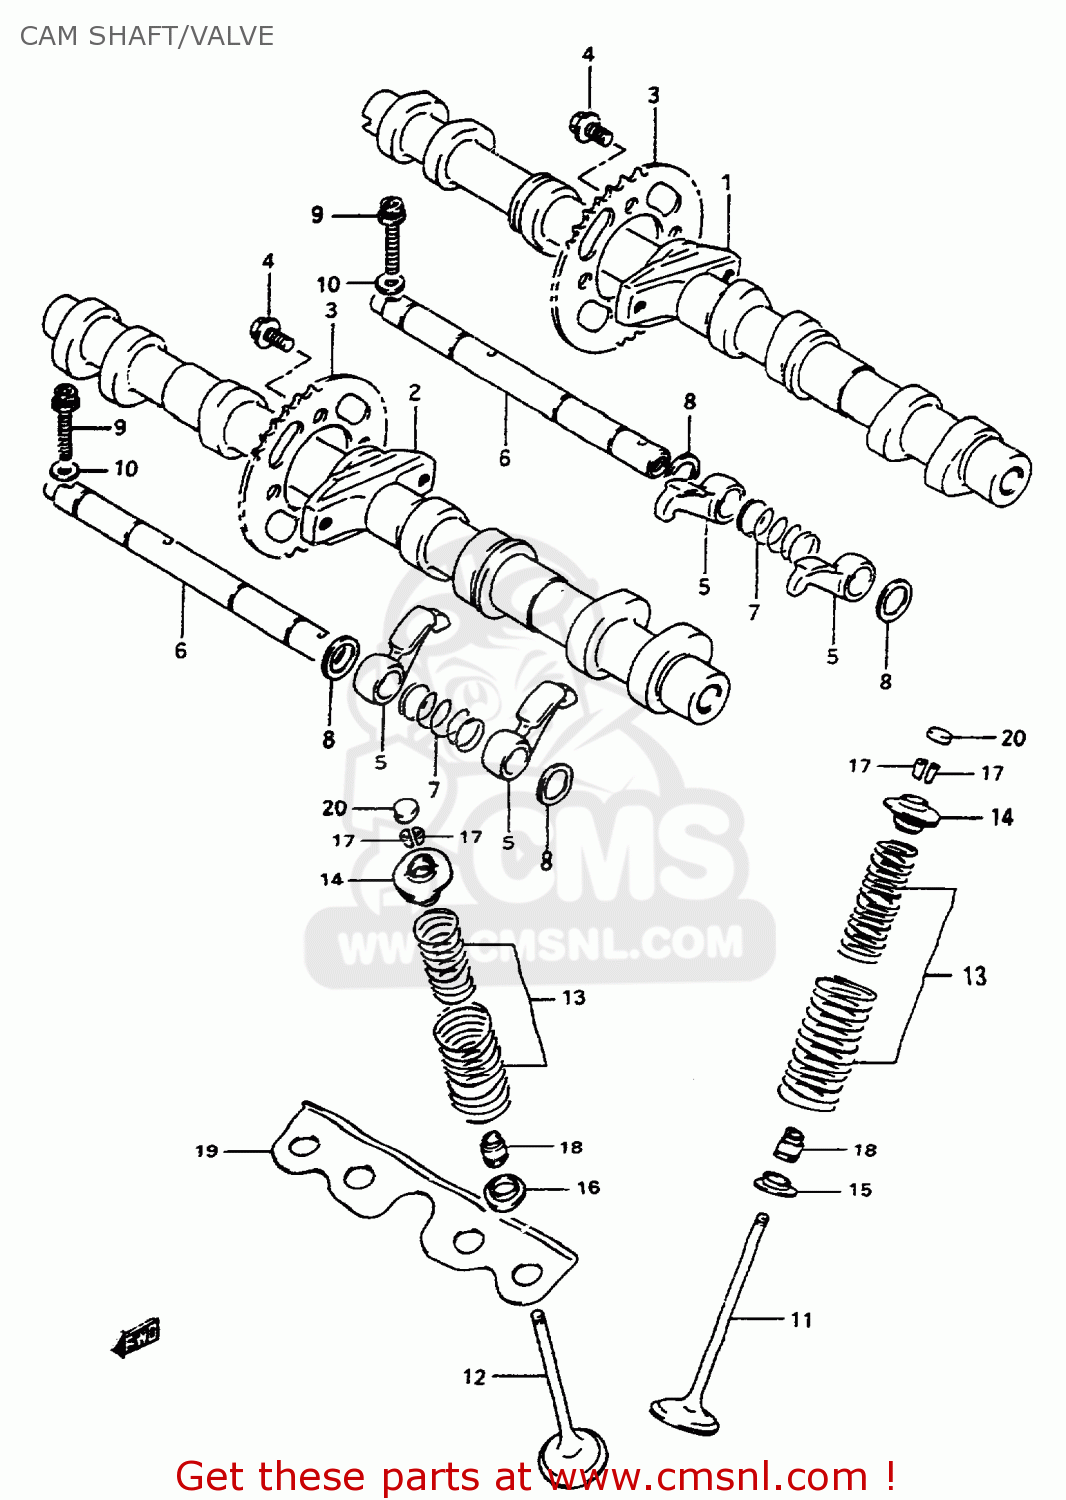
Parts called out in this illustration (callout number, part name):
1	CAMSHAFT INTAK
2	CAMSHAFT,EXHAUST
3	SPROCKET,CAMSHAFT
4	BOLT(7X11)
5	ARM,VALVE ROCKER
6	SHAFT,VALVE ROCKER ARM
7	SPRING
8	WASHER
9	BOLT,OIL PAN
10	WASHER
11	VALVE,INTAKE
12	VALVE,EXHAUST
13	SPRING SET,VALVE
14	RETAINER,VALVE SPRING
15	SEAT,VALVE SPRING
16	SEAT,VALVE SPRING EXH INNER
17	COTTER VALVE
18	SEAL,OIL(5X10X9.7)
19	PLATE,VALVE SEAT
20	SHIM,TAPPET(T:2.3)
22	CASE,TAPPET SHIM
